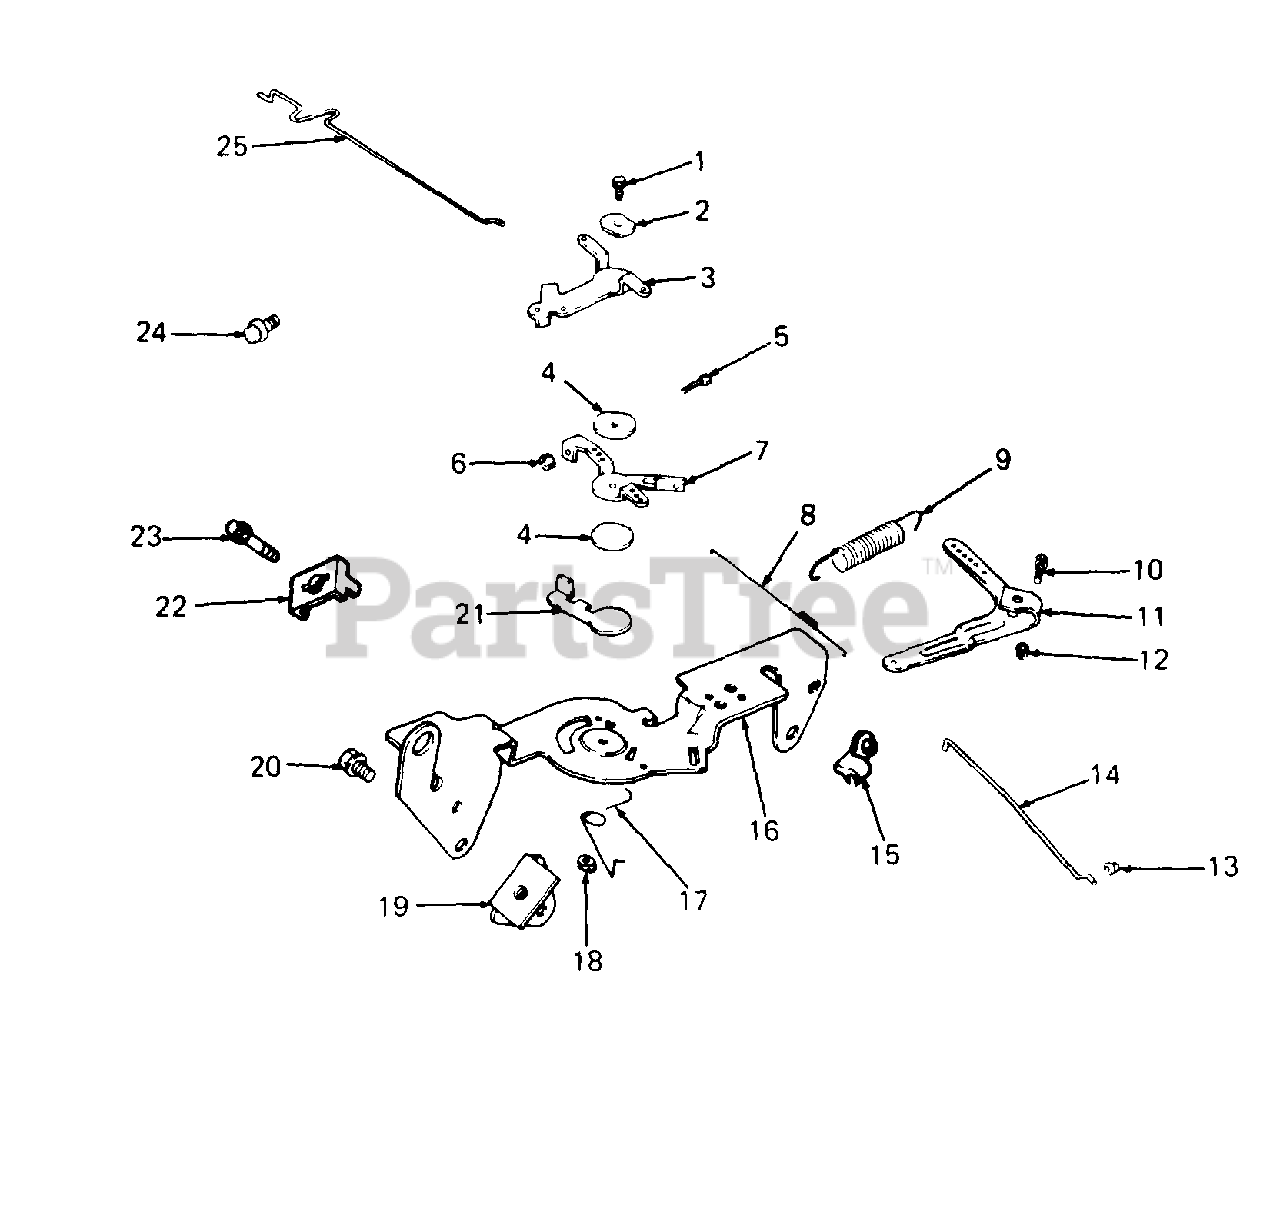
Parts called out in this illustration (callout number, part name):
1	Screw, M5 x 0.8 x 20
2	Washer, Spring
3	Lever, Choke
5	Screw, M4 x 0.7 x 27.9
6	Nut
7	Lever, Throttle Control
8	Spring, Linkage
9	Spring, Governor
10	Screw, M6 x 1.0 x 25
11	Lever, Governor
12	Nut, M6 x 1,0
13	Bushing, Linkage Retaining
14	Linkage, Throttle
15	Bushing, Linkage Retaining
16	Bracket, Control
17	Spring, Choke Return
18	Nut, M5 x 0.8
19	Bracket, Support
20	Screw, M6 x 1.0 x 16
21	Lever, Throttle Actuator
22	Clamp, Cable
23	Screw, M5 x 0.8 x 16
24	Screw, M5 x 0.8 x 10
25	Linkage, Choke
